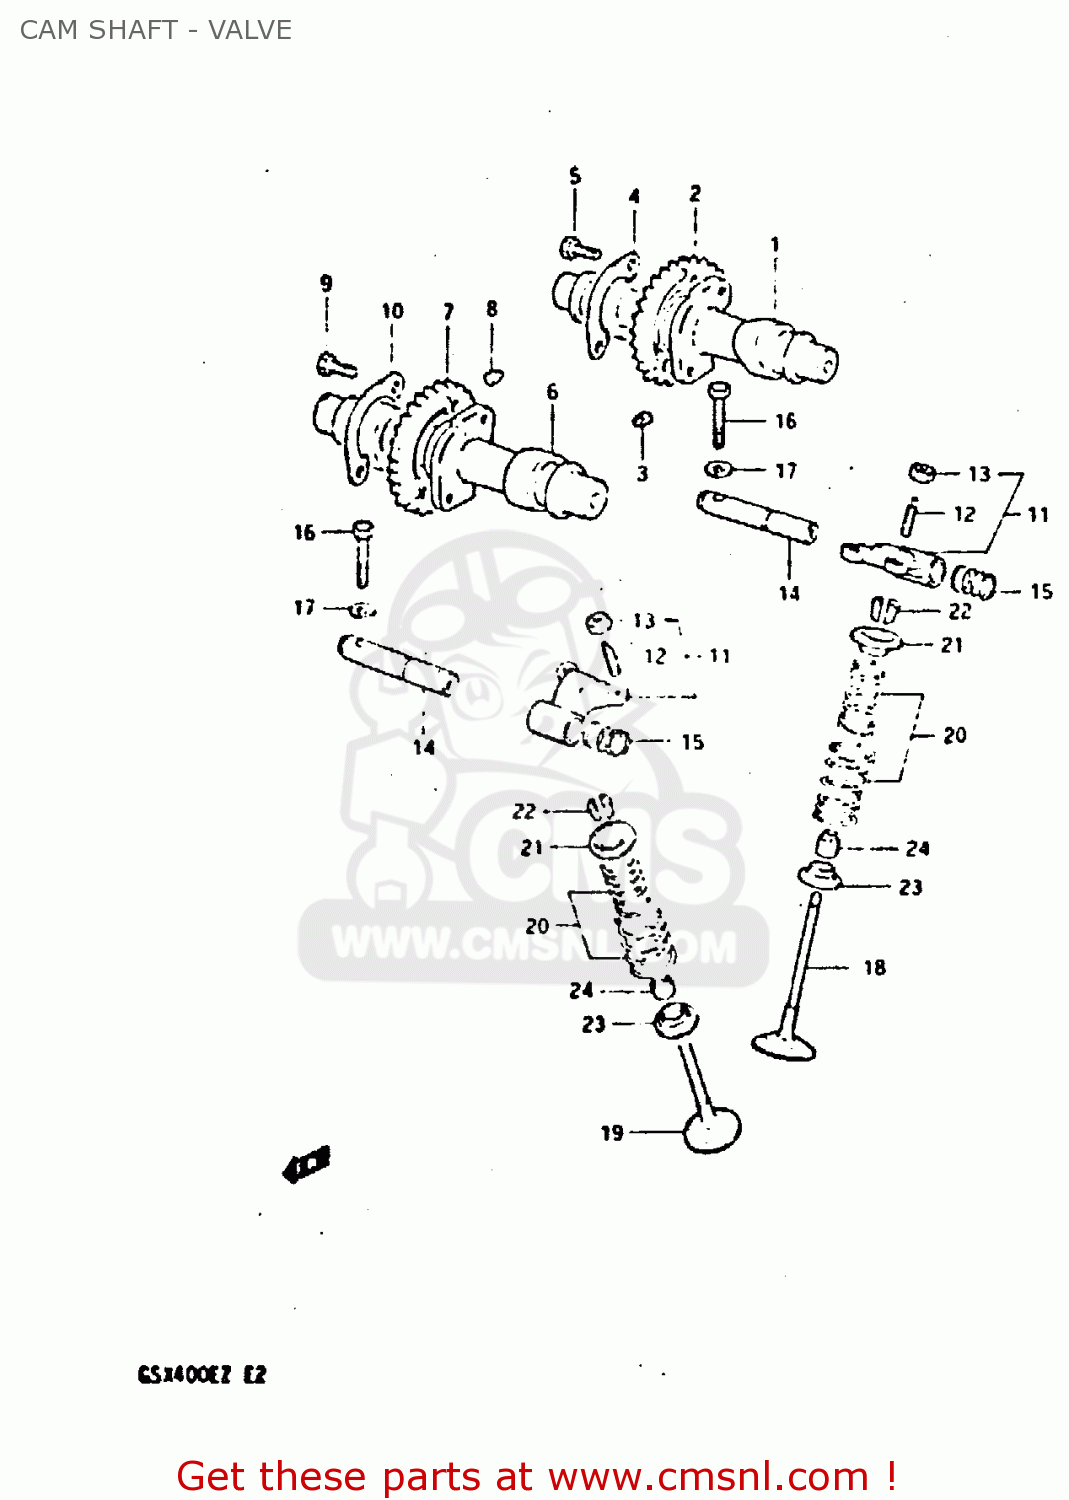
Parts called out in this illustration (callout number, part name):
1	CAM SHAFT, INTAKE
2	SPROCKET (NT:30)
3	PIN,SPROCKET
4	BOLT(6X12.5)
5	WASHER,CAM CHAIN SPROCKET
6	CAMSHAFT,EXHAUST
7	SPROCKET (NT:30)
8	PIN,SPROCKET
9	BOLT(6X12.5)
10	WASHER,CAM CHAIN SPROCKET
11	ARM,VALVE ROCKER
12	SCREW,TAPPET ADJUSTING
13	NUT,ADJUSTING
14	SHAFT,VALVE ROCKER ARM
15	SPRING
16	BOLT
17	WASHER
18	VALVE,INTAKE
19	VALVE,EXHAUST
20	SPRING SET,VALVE
21	RETAINER,VALVE SPRING
22	COTTER VALVE
23	SEAT,VALVE SPRING
24	OIL SEAL
